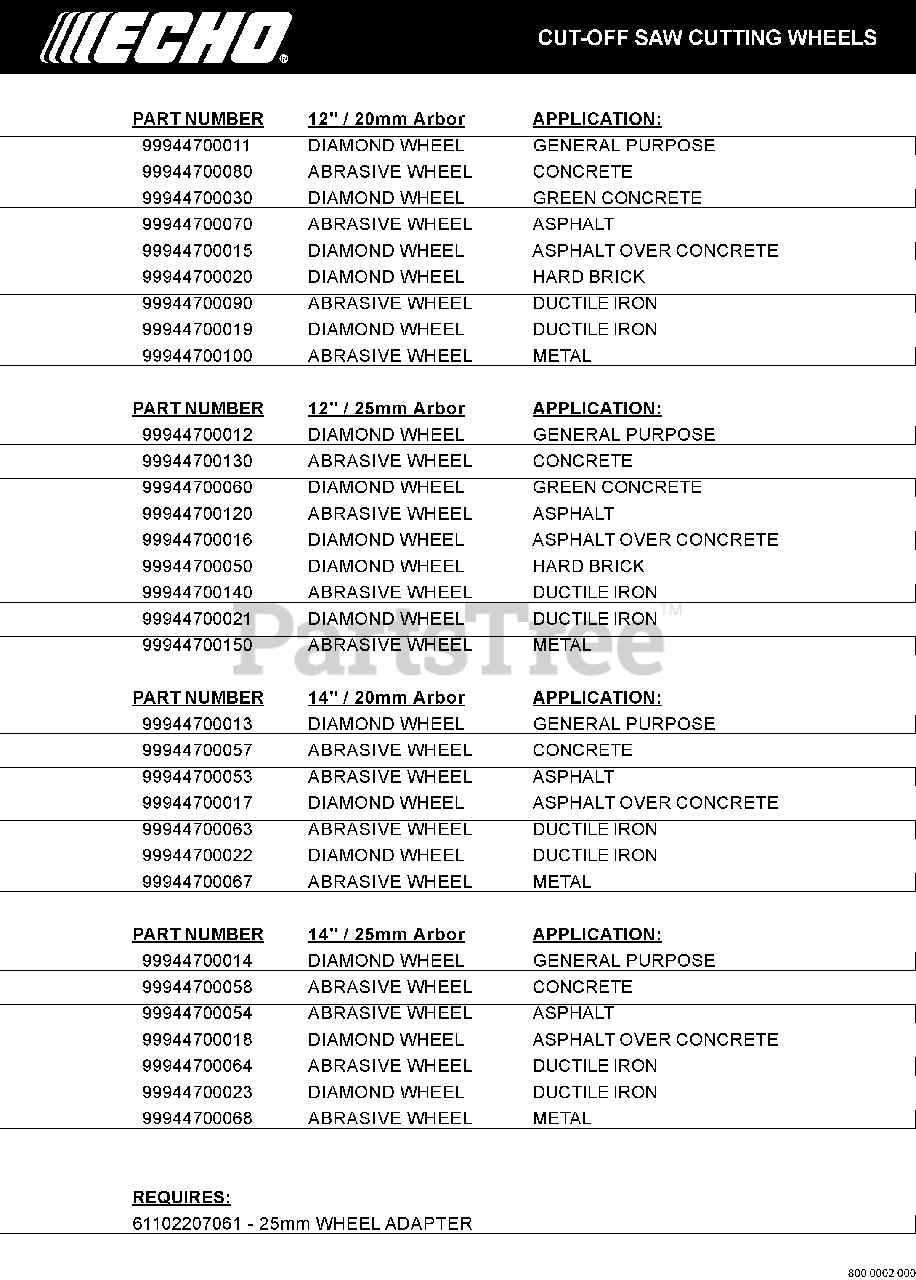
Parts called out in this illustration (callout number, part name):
1	DIAMOND WHEEL
2	ABRASIVE WHEEL - 20 MM ARBOR -- 12"
3	DRY DIAMOND WHEEL - 12", 20 MM ARBOR
4	ABRASIVE WHEEL - 20 MM ARBOR -- 12"
5	DIAMOND WHEEL
6	DRY DIAMOND WHEEL - 12", 20 MM ARBOR
7	ABRASIVE WHEEL - 20 MM ARBOR -- 12"
8	DIAMOND WHEEL
9	ABRASIVE WHEEL - 20 MM ARBOR -- 12"
10	DIAMOND WHEEL
11	ABRASIVE WHEEL - 25 MM ARBOR -- 12"
12	DRY DIAMOND WHEEL - 12", 25 MM ARBOR
13	ABRASIVE WHEEL - 25 MM ARBOR -- 12"
14	DIAMOND WHEEL
15	DRY DIAMOND WHEEL - 12", 25 MM ARBOR
16	ABRASIVE WHEEL - 25 MM ARBOR -- 12"
17	DIAMOND WHEEL
18	ABRASIVE WHEEL - 25 MM ARBOR -- 12"
19	DIAMOND WHEEL
20	ABRASIVE WHEEL
21	ABRASIVE WHEEL
22	DIAMOND WHEEL
23	ABRASIVE WHEEL
24	DIAMOND WHEEL
25	ABRASIVE WHEEL
26	DIAMOND WHEEL
27	ABRASIVE WHEEL
28	ABRASIVE WHEEL
29	DIAMOND WHEEL
30	ABRASIVE WHEEL
31	DIAMOND WHEEL
32	ABRASIVE WHEEL
33	WHEEL ADAPTER - 25 MM
